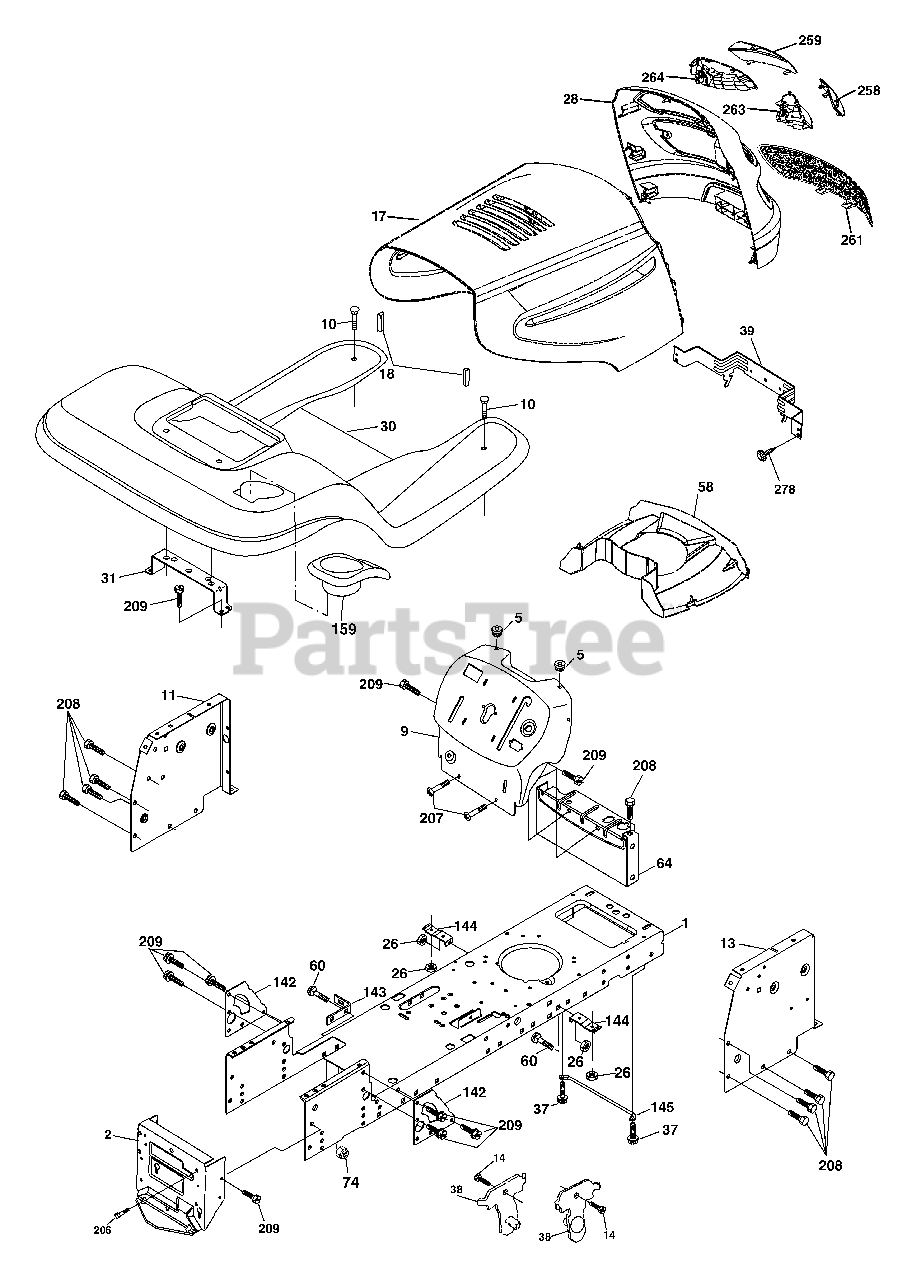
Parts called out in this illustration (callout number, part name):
1	Chassis
2	Drawbar
5	Bumper Hood/Dash
10	Bolt Carriage 3/8-16 x 1
11	Panel Dash Lh
13	Panel Dash Rh
14	Screw Thdrol 3/8-16 x 1/2
17	Hood
18	Bumper Hood
26	Nut Lock Hex W/Ins 3/8-16 unc
28	Grille/Lens Asm
30	Fender Footrest
31	Bracket Fender
37	Screw Thdrol 6/16-18 x 1/2 TYT
38	Bracket Asm Pivot Mower Rear
39	Bracket Pivot
60	Bolt RDHD Sqnk 3/8-16 unc x 3/4
64	Dash Lower STLT
74	Nut Crownlock 3/8-16 unc
90	Nut Self Thd Wsh - HD 1/4 Zinc
142	Plate Reinforcement STLT
143	Bracket Swaybar Chassis
144	Bracket Footrest Step-thru
145	Rod Pivot Chassis/Hood
159	Cupholder
206	Bolt Shoulder 5/16-18
207	Screw Thdrol 5/16-18 x 1/2
208	Screw Thdrol 3/8-16 x 1/2
209	Screw Hexwsh Thdr 3/8-16 x 3/4
217	Console Fuel Window
258	Lens Grille Pro RH
259	Lens Grille Pro LH
263	Bezel Grille LH
264	Bezel Grille RH
278	Screw 10 x 3/4 Single Lead-Hex
